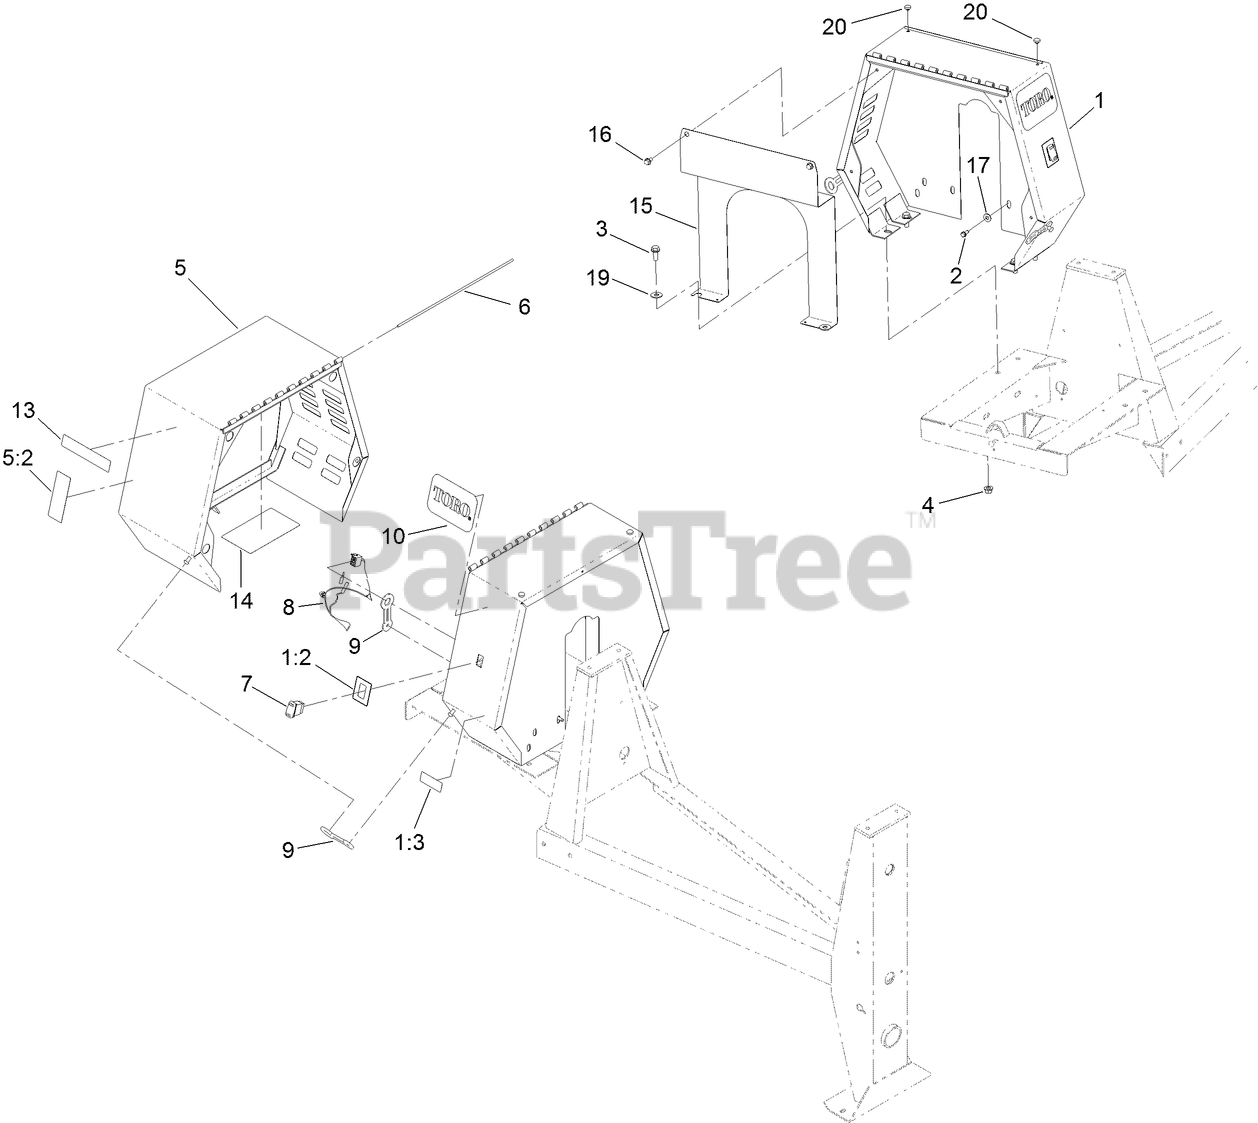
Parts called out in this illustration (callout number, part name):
1	STATIONARY COWL ASM
1:2	DECAL-STOP, ENGINE
1:3	DECAL-ARRESTER, SPARK
2	SCREW-THD ROLL, HWH
3	SCREW-HHF
4	NUT-LOCK
5	MOVABLE COWL ASM
5:2	DECAL-WARNING
7	SWITCH
8	HARNESS-WIRE, MIXER
9	LATCH-RUBBER
10	DECAL
14	DECAL-SERVICE
15	PLATE-ENGINE
16	SCREW-HWH
17	WASHER-FLAT
19	WASHER-FLAT
20	BUMPER
